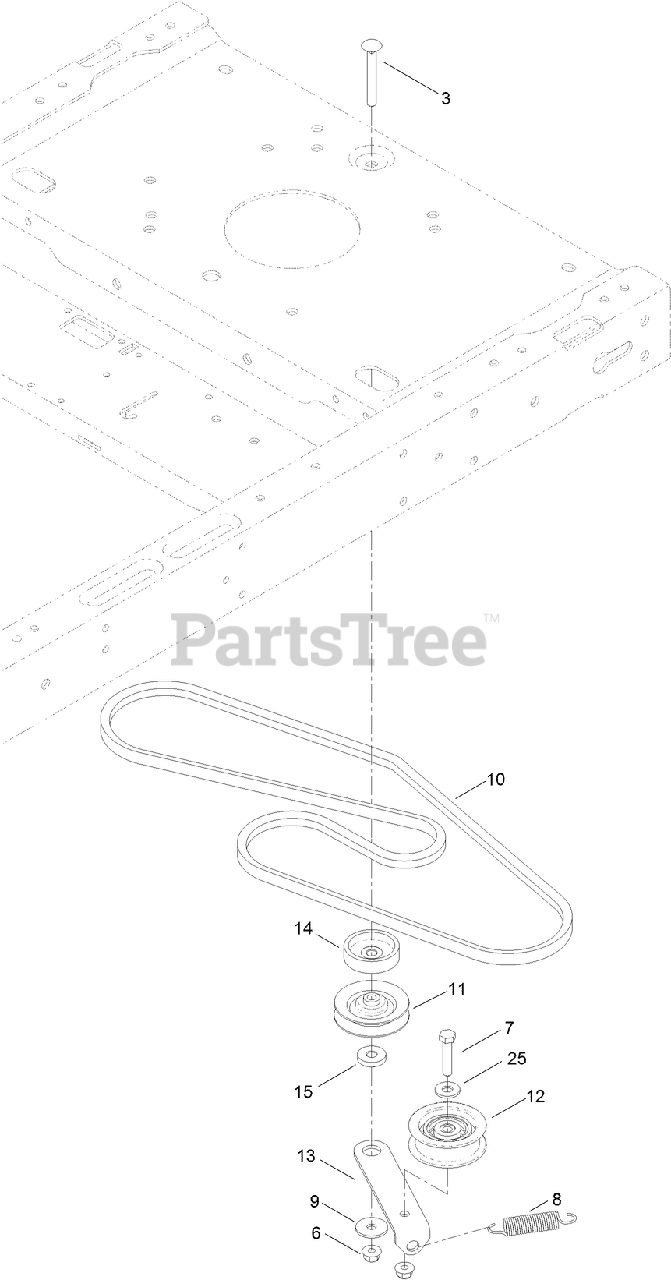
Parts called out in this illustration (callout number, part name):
3	SCREW-CARR
6	NUT-HF, NI
7	SCREW-HH
8	SPRING-RETURN, PEDAL
9	WASHER-PIVOT
10	V-BELT
11	PULLEY-IDLER
12	PULLEY-IDLER
13	ARM-IDLER
14	SPACER
15	SPACER-ARM, IDLER
25	WASHER-FLAT
